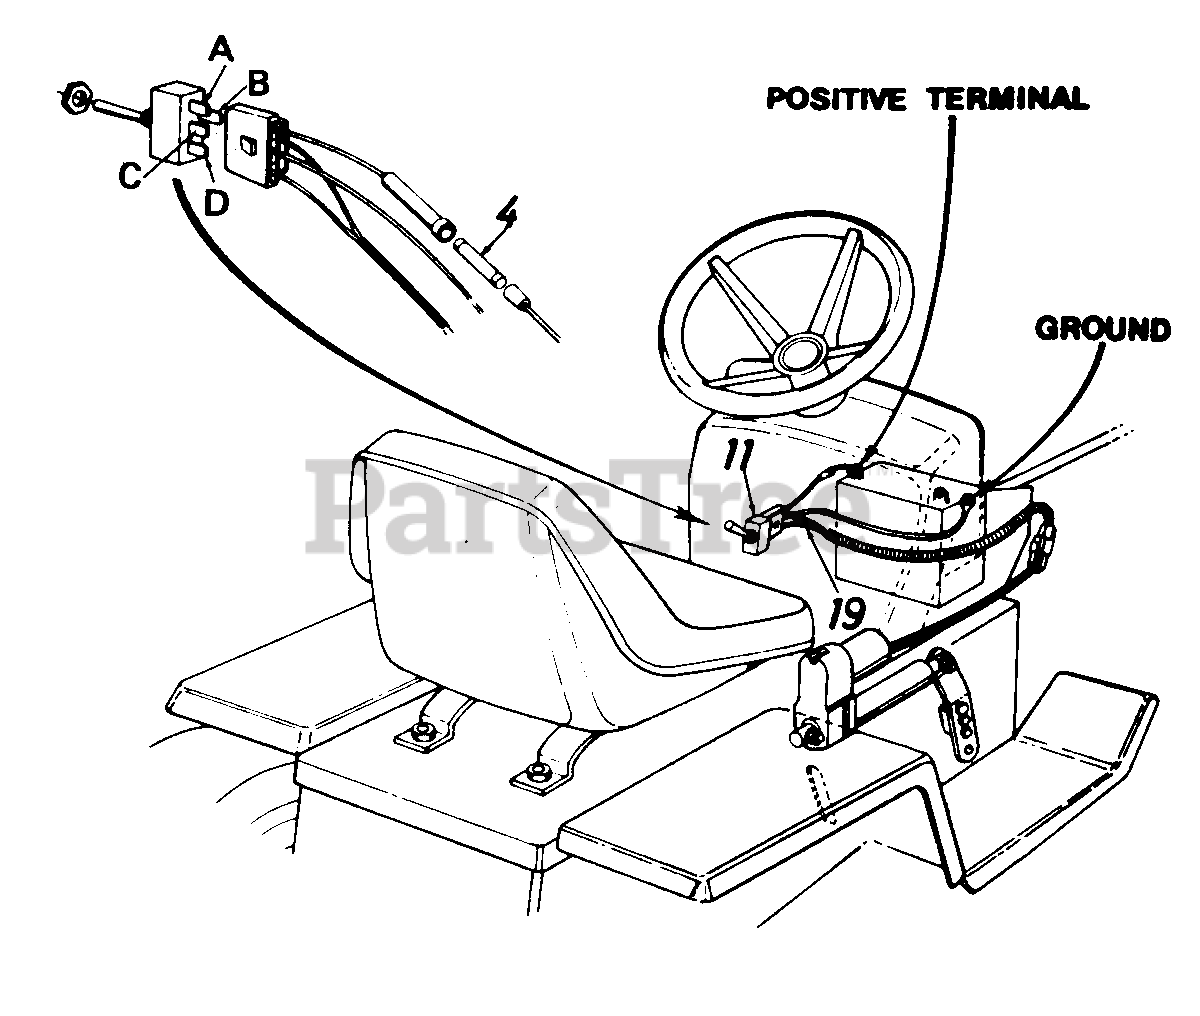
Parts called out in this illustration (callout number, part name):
4	Fuse 30 AMP
11	Toggle Switch
19	Wire Harness
A	Blue Wire Connects to Positive Terminal on Battery
B	Yellow Wire Connects to Actuator
C	Black Wire Ground Wire to Frame
D	Red Wire Connects to Actuator
